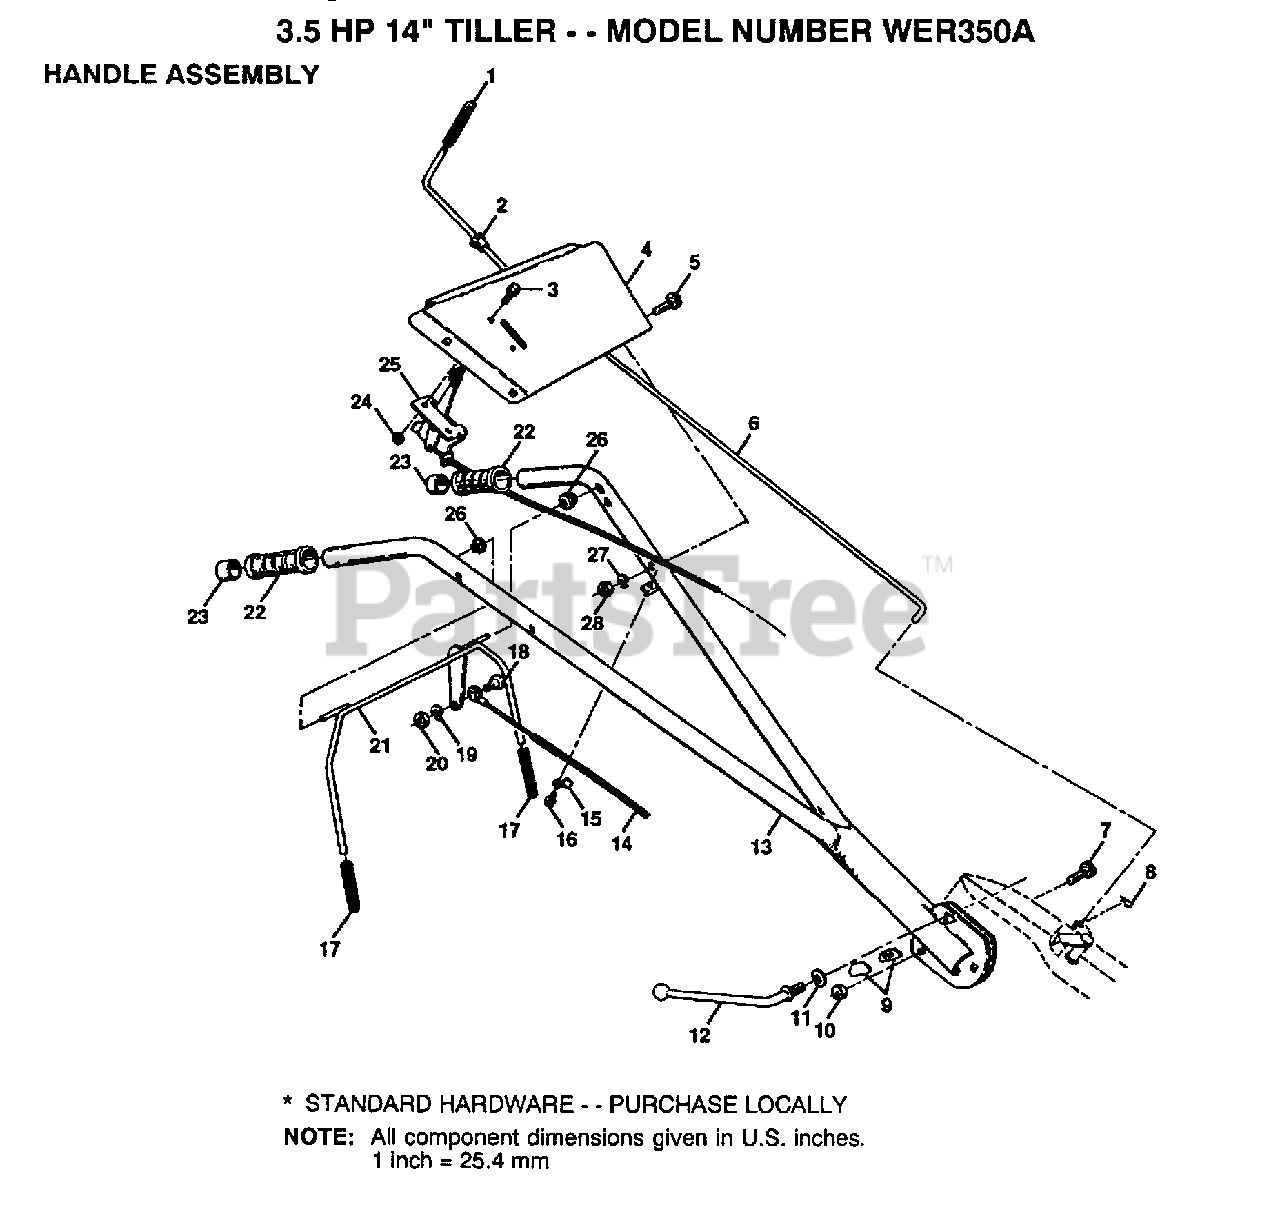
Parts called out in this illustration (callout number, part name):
1	GRIP TI
2	BUSHING
3	SCREW
5	BOLT CARRIAGE CRT
6	ROD SHIFT CRT
7	BOLT D
8	RETAINER M
9	LOCK CRT
10	LOCKNUT
11	WASHER CRT
12	LEVER LOCK CRT
14	CABLE.CLUTCH.CRT
15	CONDIUT CLIP T
17	GRIP BAR CRT
18	SHOULDER BOLT ST
19	LOCKWASHER
21	HANDLE BAR CRT
23	CAP CRT
25	"CONT,THROTTLE"
27	LOCKWASHER
